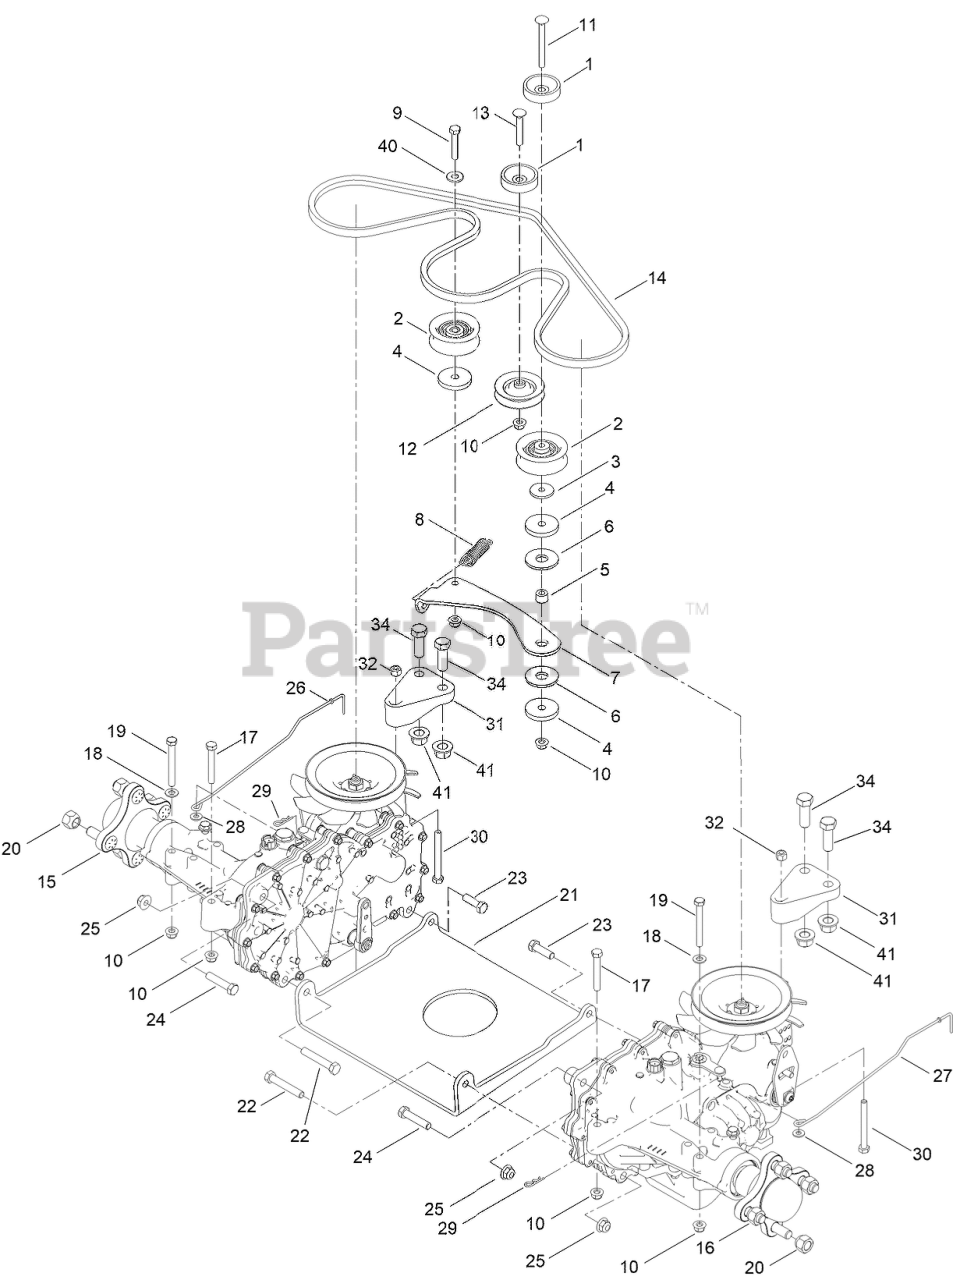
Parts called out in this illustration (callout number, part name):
1	SPACER
2	PULLEY-IDLER, FLAT
3	WASHER-FLAT
4	WASHER-PLAIN
5	BUSHING
6	WASHER-FRICTION, COMPOSITE
7	ARM-IDLER
8	SPRING-PEDAL, RETURN
9	SCREW-HH
10	NUT-HF
11	SCREW-CARR
12	PULLEY-IDLER
13	SCREW-CARR
14	V-BELT
15	RH HYDRO TRANSMISSION ASM
16	LH HYDRO TRANSMISSION ASM
17	SCREW-HH
18	WASHER-PLAIN
19	SCREW-HH
20	NUT-LUG
21	PLATE-CROSS, HYDRO
22	SCREW-HH
23	SCREW-HH
24	SCREW-HH
25	NUT-HF, NI
26	ROD-BYPASS, RH
27	ROD-BYPASS, LH
28	WASHER-FLAT
29	PIN-HAIR
30	SCREW-HH
31	SUPPORT-HYDRO, REAR
32	NUT-HEX
34	SCREW-HH
40	WASHER-FLAT
41	NUT-HF
